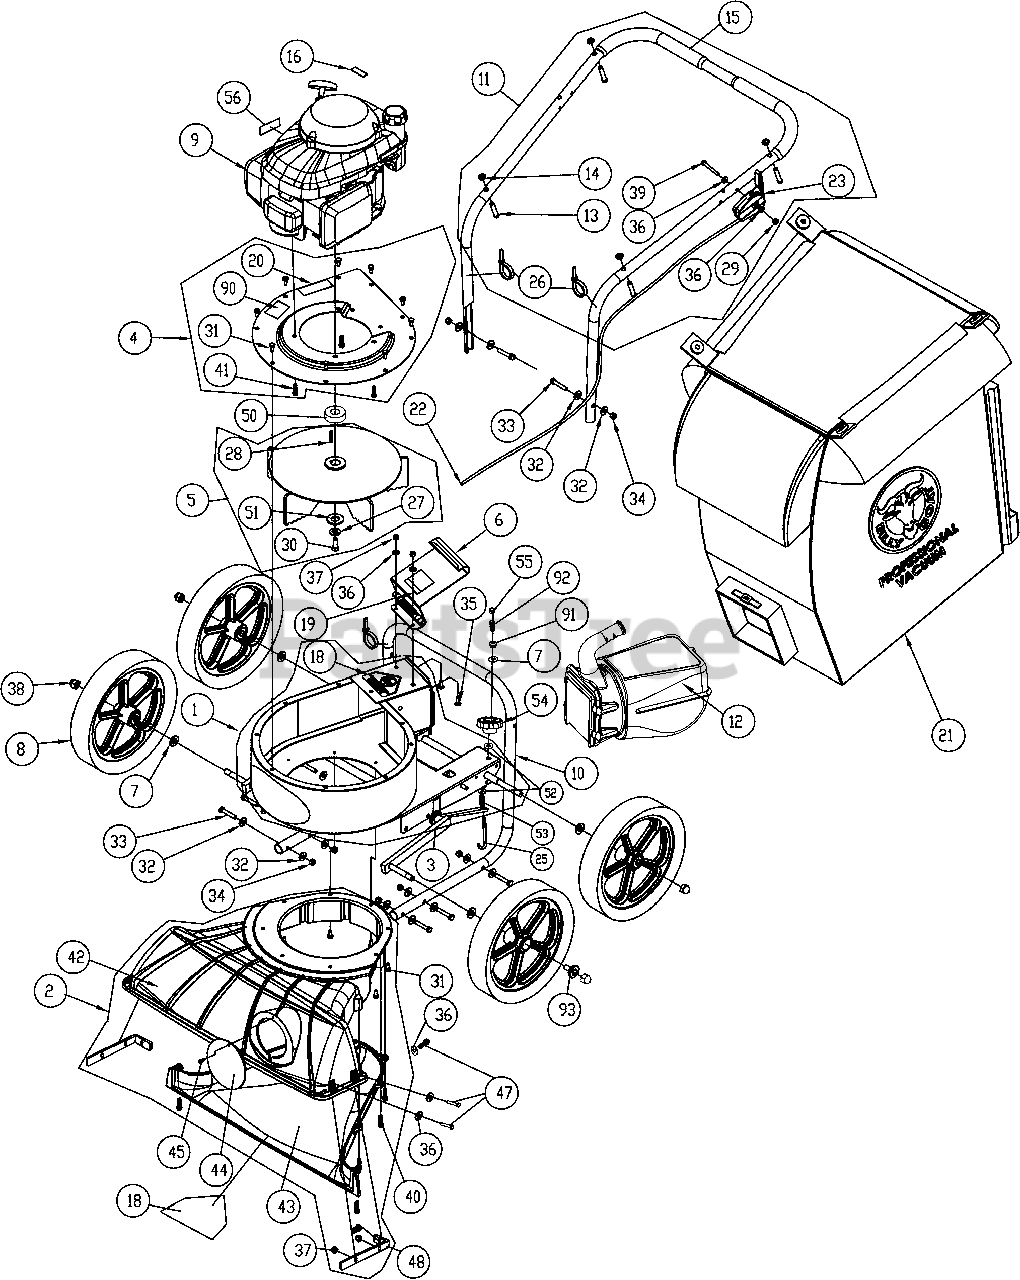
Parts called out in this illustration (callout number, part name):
1	MAIN FRAME HOUSING NEW KD
2	NOZZLE ASSEMBLY TKV
3	AXLE WA KV MICRO
4	PLATE TOP ENGINE KV
5	IMPELLER 12.75 WA PUSH VAC
6	DOOR EXHAUST ASSY RAW
7	WASHER 1/2" SAE Z/P
8	WHEEL ASSY 12" X 2.5" TREAD
9	ENGINE 6.5 HP HONDA GSV190AN1L
10	LOWER HANDLE KV
11	HANDLE UPPER KV
12	QUICK DISCONNECT
13	PIN CLEVIS 3/8" x 2.125" LONG
15	GRIP HANDLE 1"X 9.5" LG
16	LABEL WARNING FUEL EN/SP
18	LABEL WARNING DANGER
19	LABEL DANGER FLYING DEBRIS
20	LABEL SAFETY PROTECT READ MANUAL
21	BAG FELT W/SKIRT (FB MODELS)
23	CABLE THROTTLE ASSY 42" W/CHOKE
25	BOLT J 3/8-16 X 6"
27	WASHER LOCK 3/8" ST MED
28	KEY 3/16 SQ. X 1.25
29	NUT 1/4-20 ACORN
30	SCREWCAP 3/8-24X1 1/2" GR. 8
31	SCREWCAP 1/4 - 20 x 5/8 HWH
32	WASHER 5/16 FLATWASHER Z/P
33	SCREWCAP 5/16-18 X 1.75 ZP
34	NUT LOCK 5/16-18
35	SCREWCAP 1/4-20 X 3/4"
36	WASHER 1/4" SAE ZP
37	NYLON INSERT LOCKNUT, 1/4-20 UNC
38	1/2-13 CAP NUT NP W/PATCH
39	SCREWCAP 1/4-20x2" HCS ZP
40	SCREW PLASTIC 1/4-10 X 1
41	SCREW 3/8 x 1 1/2 TAPTITE
42	NOZZLE TOP HALF KV
43	NOZZLE BOTTOM HALF KV
44	PLUG HOUSING KD LB
45	SCREW SELF TAPPING 10-24 X 1/2
46	LABEL KV PUSH
47	SCREWCAP 1/4-20 X 1"
48	BRACKET NOZZLE KV
50	SPACER 1.5 OD X .875 ID X .975 THK
51	WASHER 1.5 OD X .453 ID X .25 THK
52	WASHER 1/2" FC
53	SPRING COMPRESSION
54	KNOB 3/8-16 RED
55	NUT LOCK 3/8-16 THIN
56	LABEL SPARK ARRESTOR EN/SP
90	LABEL MADE IN U.S.A.
91	GROMMET FLANGE 1/2" MOLDED
92	SPRING COMPRESSION
93	BEARING BALL FLANGED
